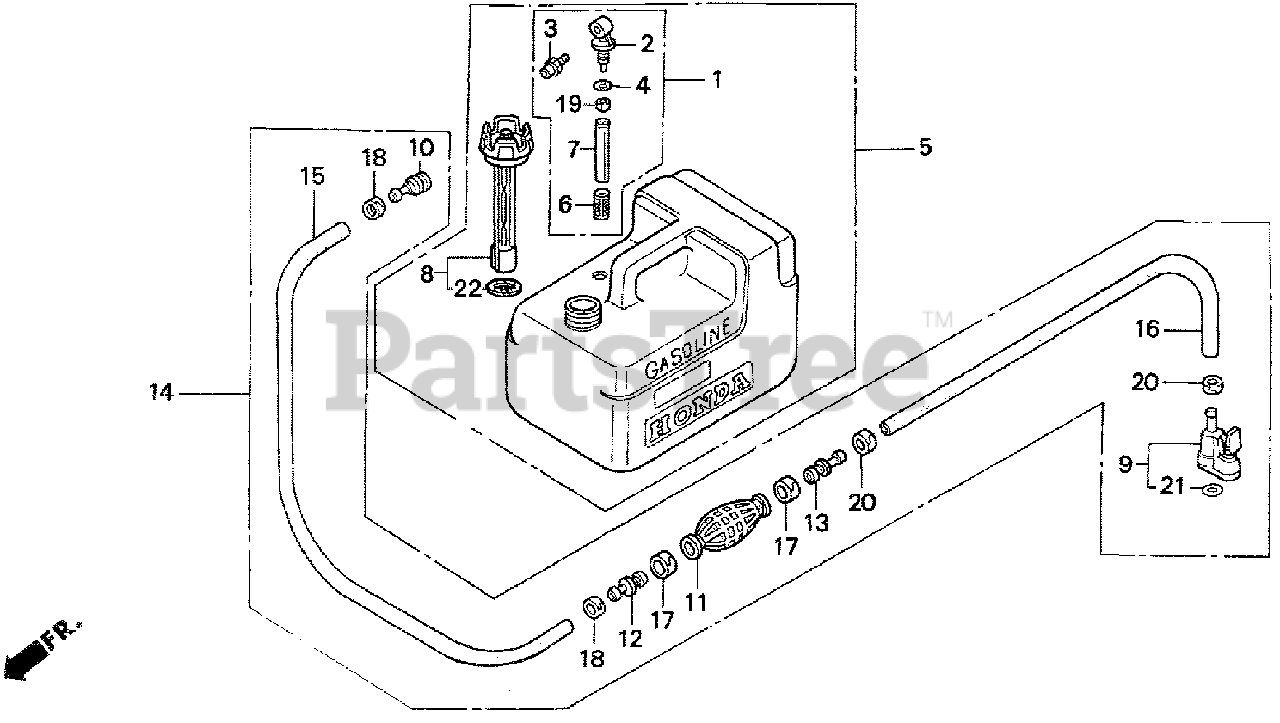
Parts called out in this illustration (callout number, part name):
1	JOINT ASSY., FUEL
3	FITTING, QUICK DISCONNECT
4	O-RING
5	TANK ASSY., FUEL
6	FILTER, FUEL
8	CAP, FUEL FILLER
9	CONNECTOR, FUEL *NH1* (BLACK)
10	CONNECTOR, FUEL
11	PRIMER BULB
12	VALVE, IN.
13	VALVE, OUTLET
14	TUBE, FUEL *NH1* (BLACK)
15	TUBE, FUEL LONG (7.5X2000)
16	TUBE, FUEL SHORT
17	BAND, TUBE CLIP (20MM)
18	BAND, TUBE CLIP (12.5MM)
20	BAND, TUBE CLIP (11MM)
21	O-RING (5.5X3)
22	GASKET, FUEL CAP
